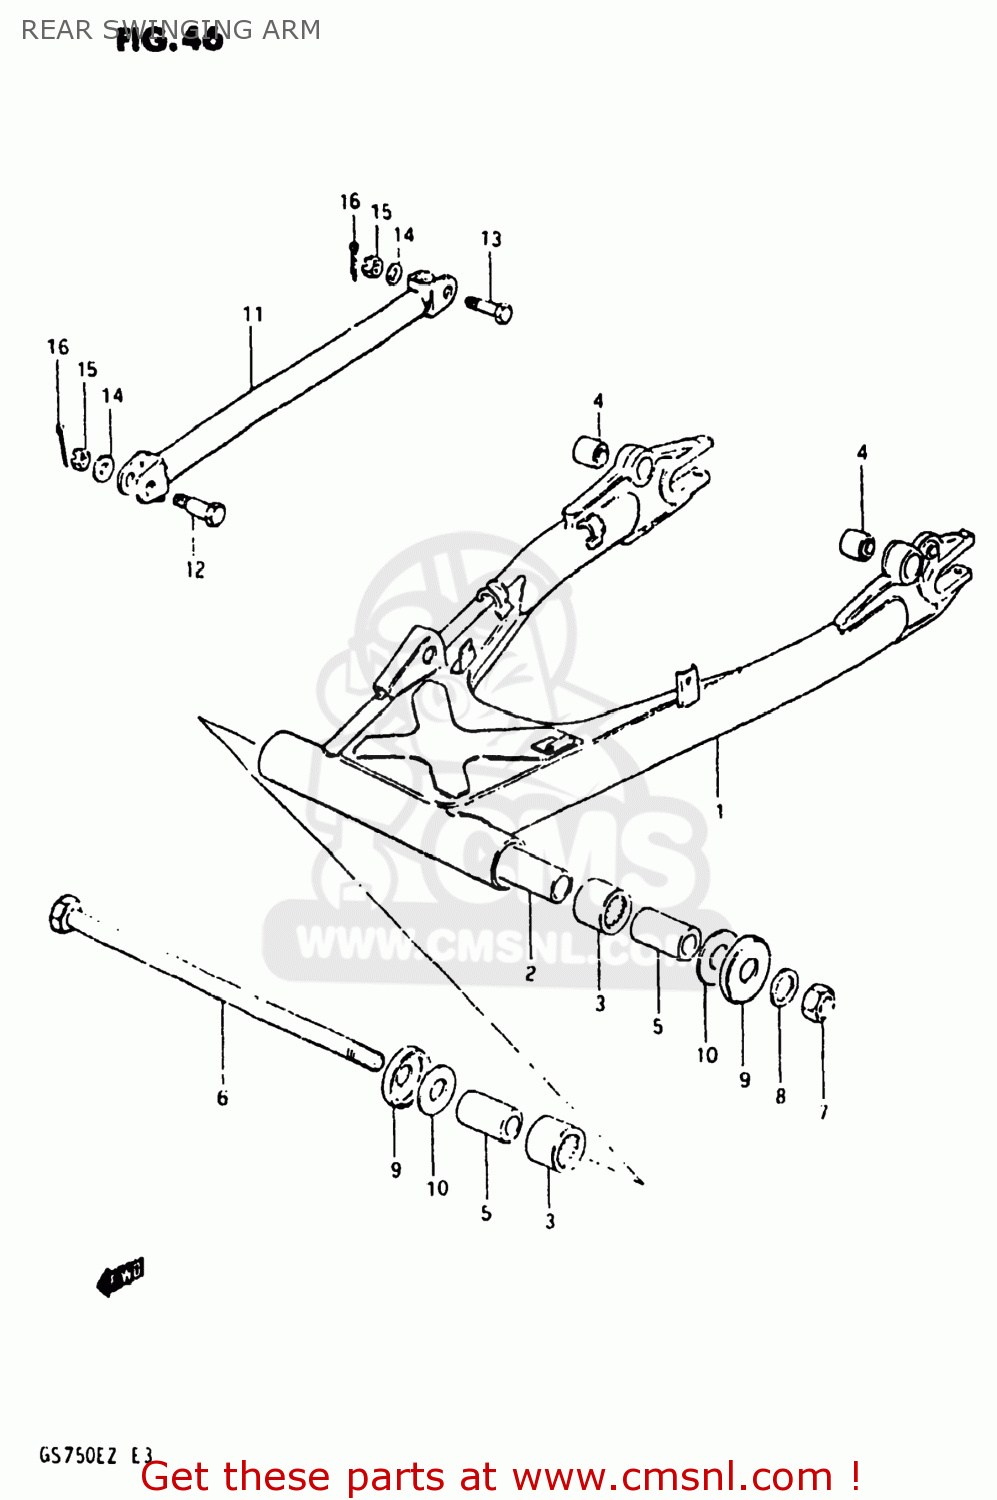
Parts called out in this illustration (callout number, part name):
1	ARM,REAR SWING
2	SPACER,RR SWGARM PIVOT CTR
3	BEARING(22X29X30)
4	BUSH
5	SPACER,RR SWGARM PIVOT
6	SHAFT,REAR SWING ARM
7	NUT 14MM
8	WASHER
9	CVR,RR SWGARM DUST SEAL(OD:40)
10	WASHER(14.2X34X1)
11	LINK,REAR TORQUE
12	BOLT
13	BOLT(10X39)
14	WASHER
15	NUT
16	PIN 20X20
